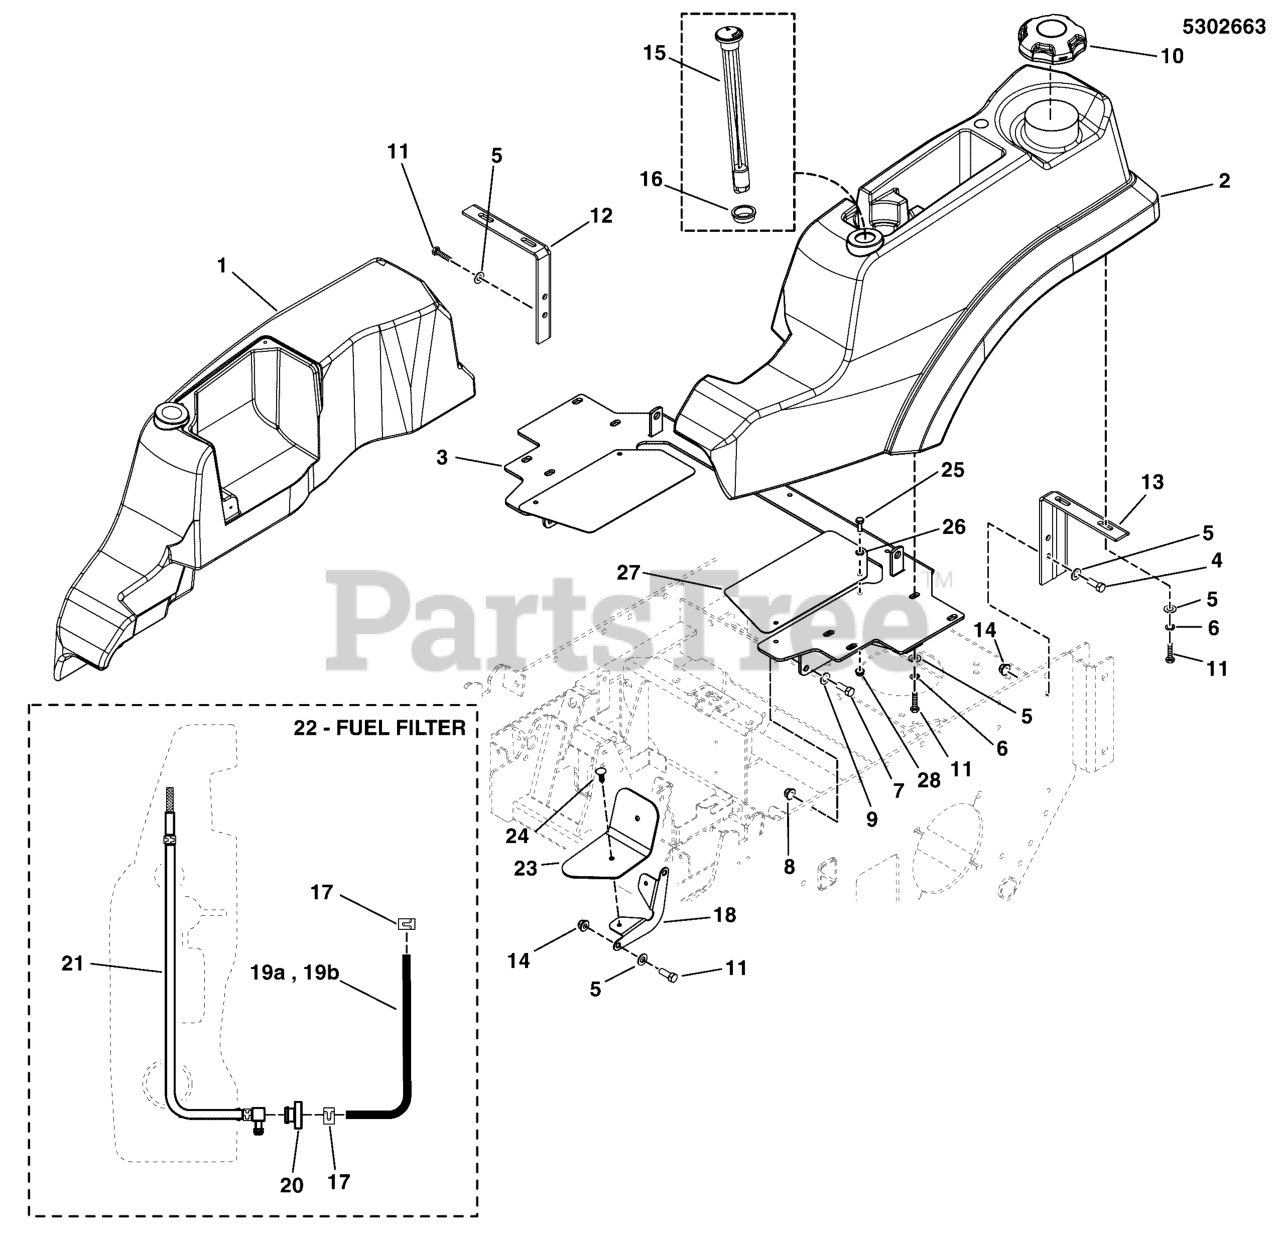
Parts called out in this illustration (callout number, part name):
1	TANK, FENDER, SNAPPER PRO - RH
2	TANK, FUEL, SNAPPER PRO - LH
3	WELD, TANK MOUNT - RED
4	BOLT, 5/16-18 X 1 GD5 YZ
5	WASHER, 5/16" SAE
6	WASHER, 5/16 LOCK CZ
7	BOLT, 3/8-16 X 1" GD5 CZ
8	NUT, 3/8-16 HEX NYLOCK FLANGE
9	WASHER, 3/8 SAE
10	CAP, GASOLINE
11	BOLT, 5/16-18 X 3/4 GD5
14	NUT, 5/16-18 HEX NYLOCK FLANGE
15	GAUGE, FUEL, 12
16	GROMMET, FUEL GAUGE (SV)
17	CLAMP, HOSE, EXTERNAL, 1/2 - RED
18	MOUNT, GUARD, MOTION CTRL - BLK
20	BUSHING-FUEL TANK RED RUBBER
21	PICK UP TUBE ASSEMBLY, FUEL LINE (SV)
22	FUEL FILTER (SV)
23	FLAP, RUBBER, MOTION CONTROL, S150XT
24	PUSH RIVET (TREE TYPE), BLACK
25	BOLT, 1/4-20 X 3/4 GD5 YZ
26	WASHER, 1/4 SAE
27	PLATE, GUARD, SEAT - RED
28	NUT, 1/4-20 HEX NYLOCK FLANGE
